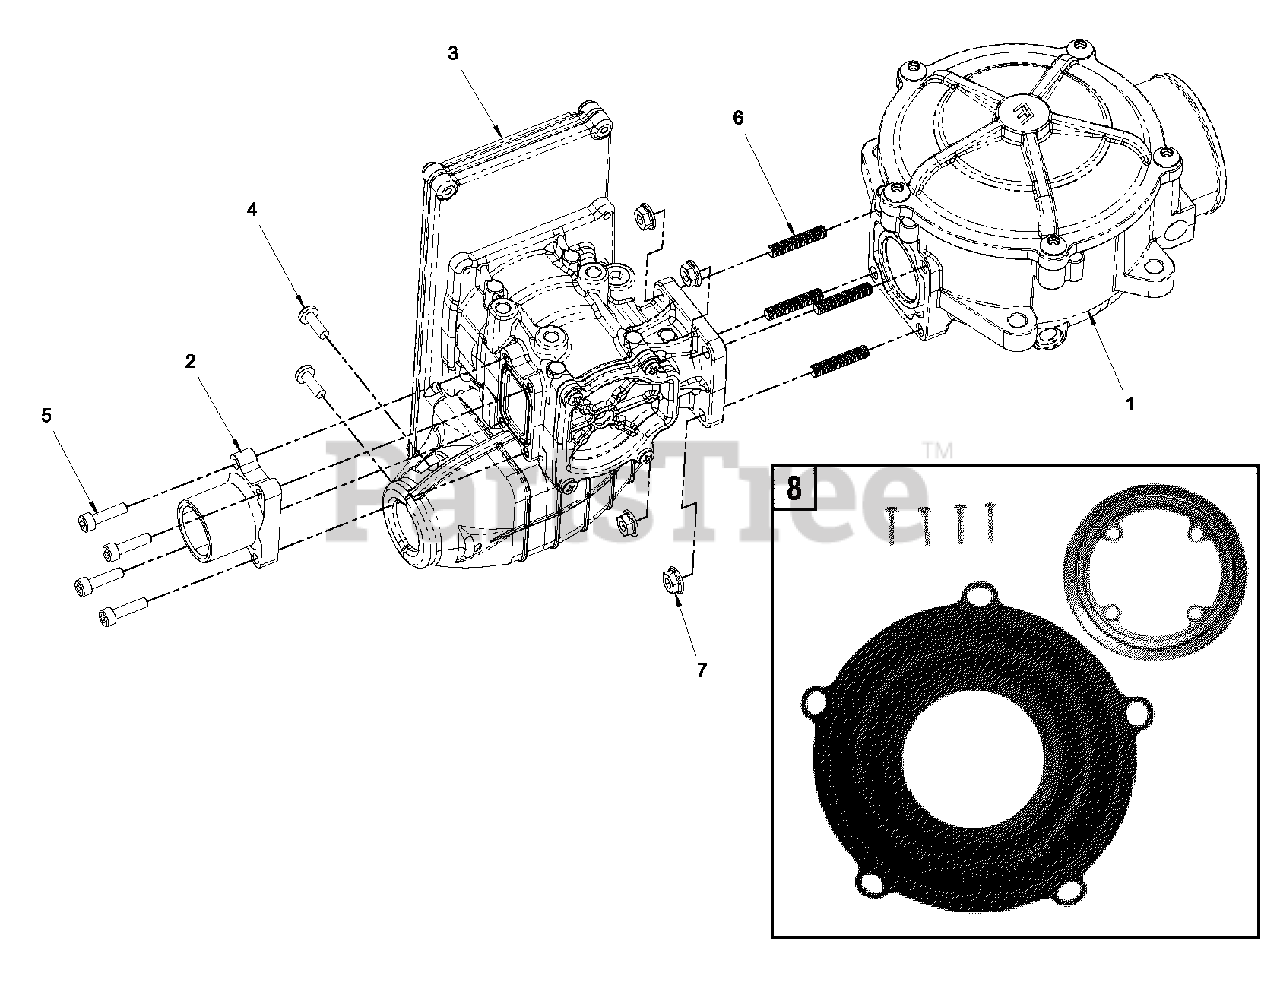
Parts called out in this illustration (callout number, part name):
3	PROGRAMMED EPR
4	* SCREW
5	* BOLT
6	* STUD
7	* NUT
8	MIXER REPAIR KIT
